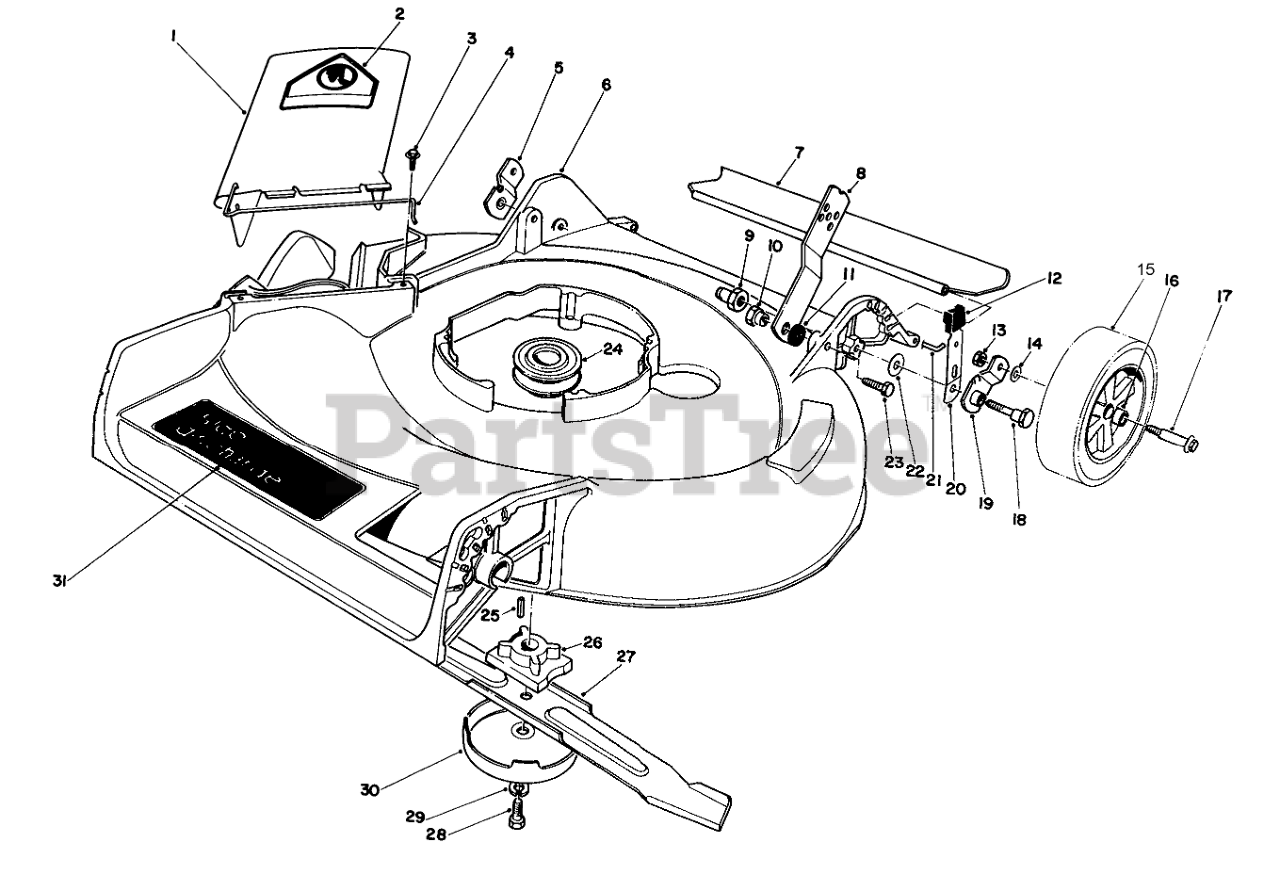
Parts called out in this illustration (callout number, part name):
1	Deflector Assembly (Incl. Ref. #2 & 4)
2	DECAL-DANGER
3	SCREW-HWH
4	SPRING HINGE
5	Pivot Arm
6	Housing
7	REAR SAFETY SHIELD 21
8	Handle Latch
9	HANDLE PIVOT NUT
10	HANDLE PIVOT NUT
11	SPACER
12	KNOB-ARM
13	Nut
14	WASHER
15	Wheel & Tire Assembly (Incl. Ref. #16)
16	BUSHING
17	BOLT-WHEEL
18	5/16-18 PIVOT SCREW
19	Pivot Arm
20	SPRING ARM ASM
21	SHIELD ROD
22	WASHER-PIVOT
23	SCREW-HH
24	Pulley-Driver
25	Key Square
26	Blade Retainer
27	Blade
28	SCREW-HH
29	WASHER-LOCK
30	Anti Scalp Cup
31	Decal-Side Discharge
